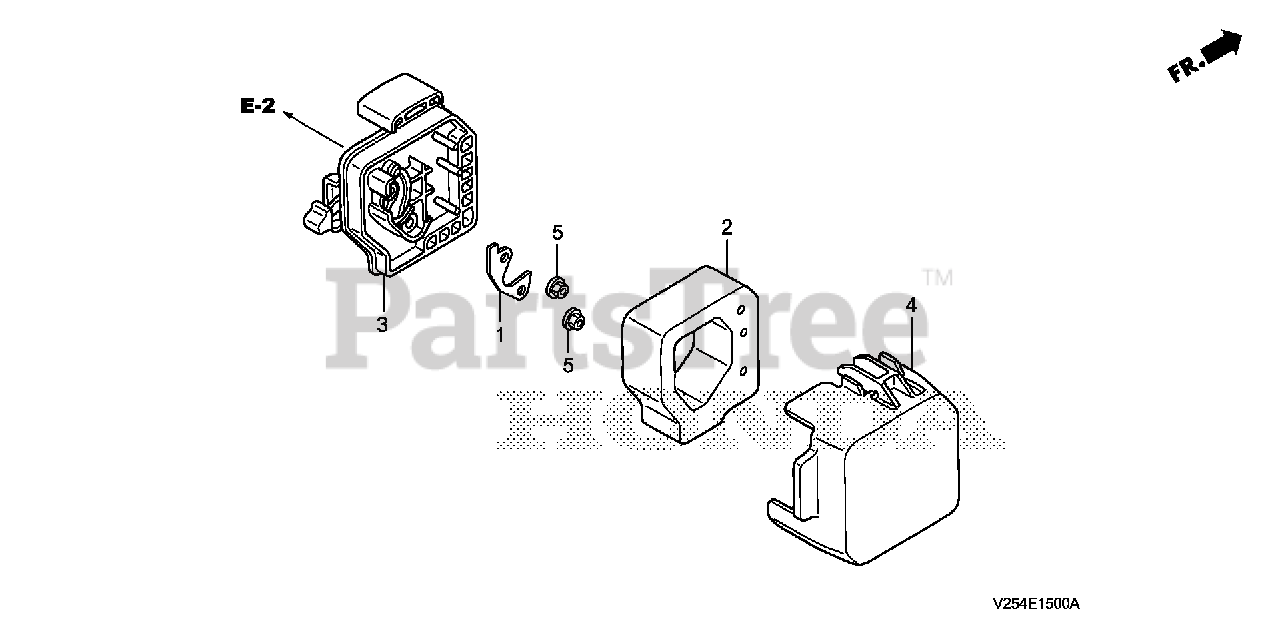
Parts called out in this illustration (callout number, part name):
1	PLATE, OIL TRAP
2	ELEMENT, AIR CLEANER
3	HOUSING, AIR CLEANER
4	COVER, AIR CLEANER
5	NUT, FLANGE (5MM)
